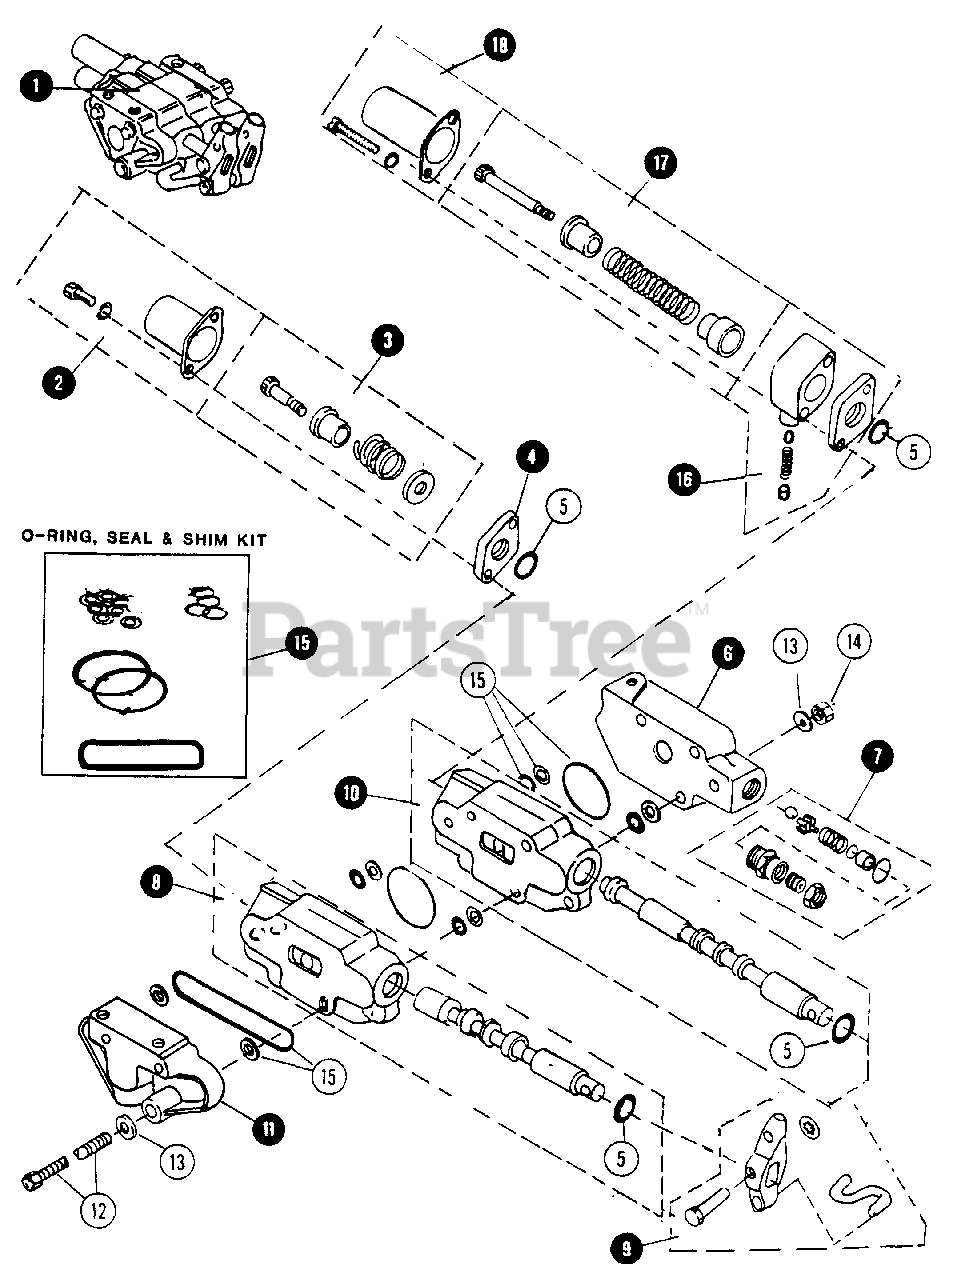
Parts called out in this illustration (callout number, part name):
1	VALVE ASSEMBLY, 2 SPOOL
2	KIT, SPOOL CAP REPLACEMENT
3	KIT, SPOOL SPRING REPAIR
4	SPACER, SPOOL
5	O-RING
6	COVER ASSEMBLY
7	KIT, RELIEF VALVE REPAIR
8	KIT, AUXILIARY VALVE REPLACEMENT
9	KIT, HANDLE CONTROL REPAIR
10	KIT, MID/FRONT LIFT VALVE REPLACEMENT
12	BOLT, 1/4 NF x 4-3/4 HEX HEAD
13	WASHER, FLAT
14	NUT, 1/4 NF HEX
15	KIT, SEAL & SHIM REPAIR
16	KIT DETENT REPAIR
17	KIT, DETENT SPOOL SPRING REPAIR
18	KIT, SPOOL CAP REPLACEMENT
